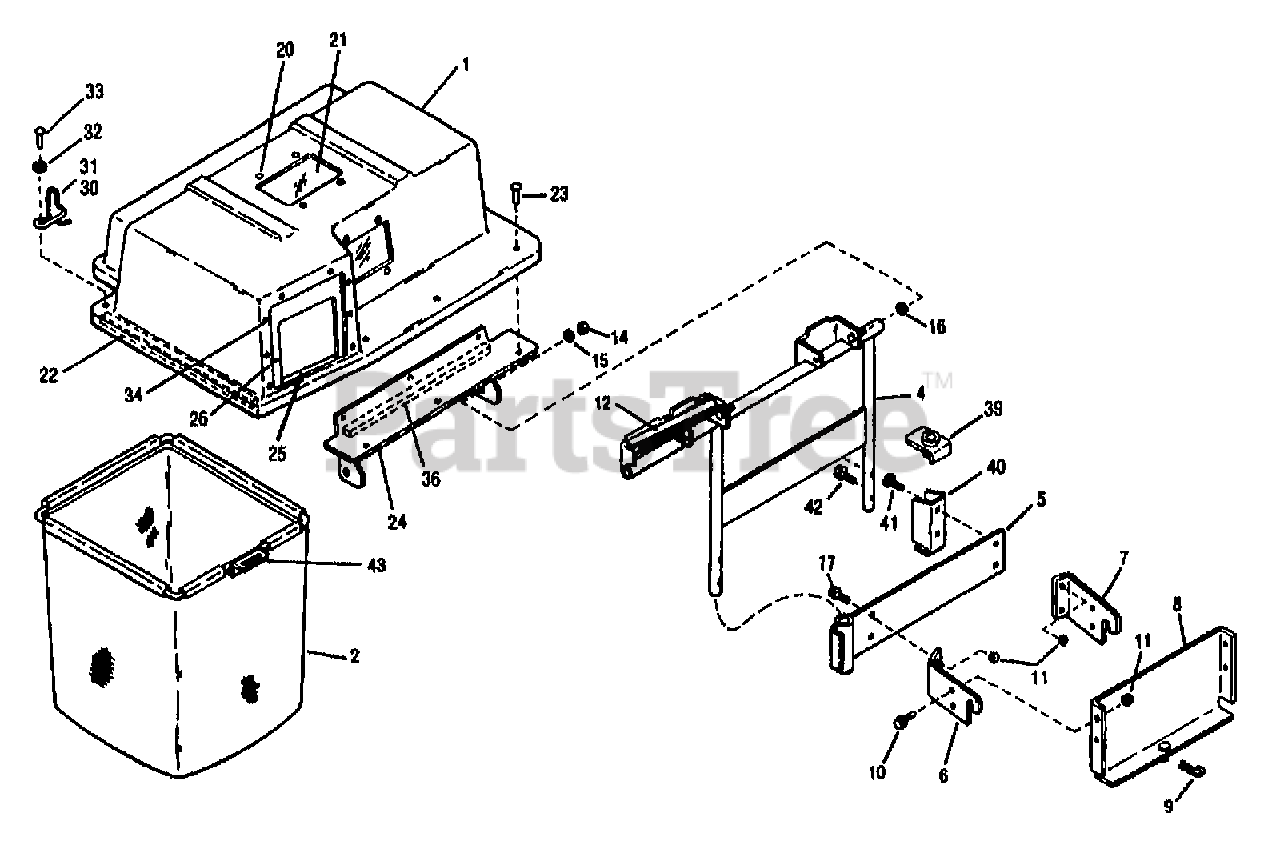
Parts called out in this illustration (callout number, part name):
1	ASSM-CVR GRASS BAG
2	ASSM-GRASS BAG
4	ASSM-BAG SUPPORT
5	ASSM-SUPPORT PLATE
6	PLATE-RIGHT HITCH
7	PLATE-HITCH LH
8	ASSM-SUPPORT HITCH
9	PIN-HITCH .125X2.56 ZP
10	SCR-HFLK 5/16-18X.75 ZP
11	NUT-HFLK 5/16-18 ZP
12	SEAL-COVER 9.5"
14	NUT-TOP/LK 5/16-18 ZP
15	WASHER-FLAT 5/16 SAE
16	WASHER-.87X.34X.06 NYLON
17	SCR-HFLK 5/16-18X1.00 ZP
20	RIVET-POP
21	WINDOW
22	SEAL-COVER
23	RIVET-POP 3/16"DIA
24	ASSM-HINGE SUPPORT
26	GASKET-CHUTE
30	COVER-LOCK RH
31	COVER-LOCK LH
32	WASHER-.88X.2X.059
33	RIVET-POP 3/16X1/2
34	RIVET-POP .125
36	SEAL-COVER
39	ASSM-COLLAR STOP
40	SUPPORT-TUBE
41	SCR-CARR 5/16-18X1.0 G2 ZP
42	SCR
43	ASSM-FRAME GRASSBAG
